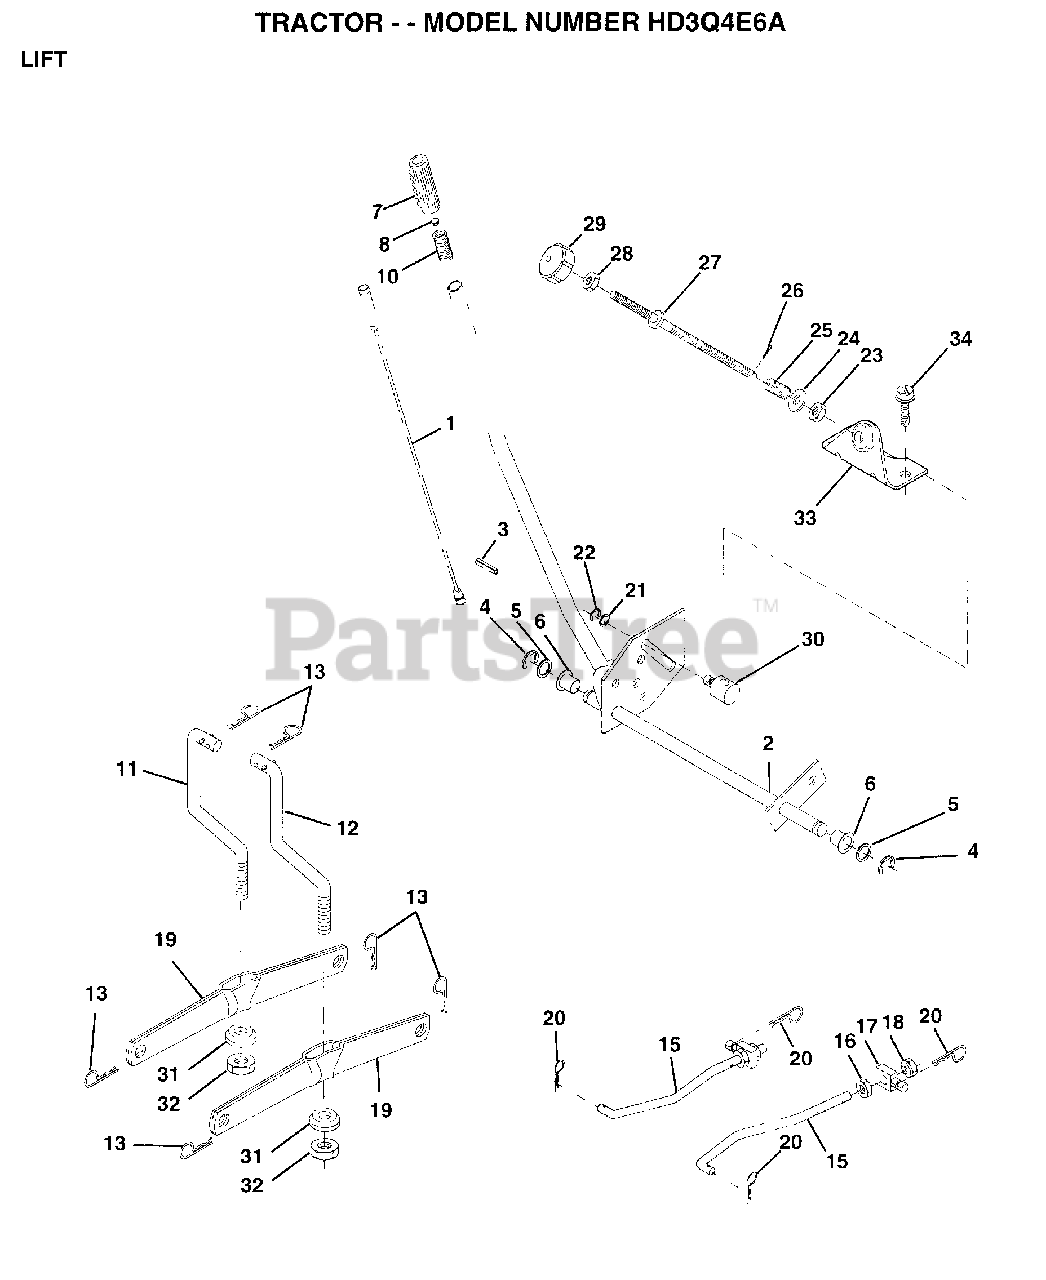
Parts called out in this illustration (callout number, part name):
1	WIRE ASM
2	HANDLE.LIFT.LH.
3	PIN GROOVE
5	WASHER
6	NYLON BEARING
7	GRIP HANDLE
15	LINK.FRONT
16	NUT
17	TRUNION
18	NUT.LK.W/WSH.1/2.
19	ARM SUSP REAR
20	RETAINER.SPRING
21	WASHER
22	KLIP RING
23	NUT T
24	WASHER
25	SPRING T
28	NUT
29	KNOB INF 3/8-16
30	TRUNION LT
31	BEARING PVT LH
32	NUT.CROWNLOCK.3/8
33	BRACKET STOP INF
34	SCREW LT
